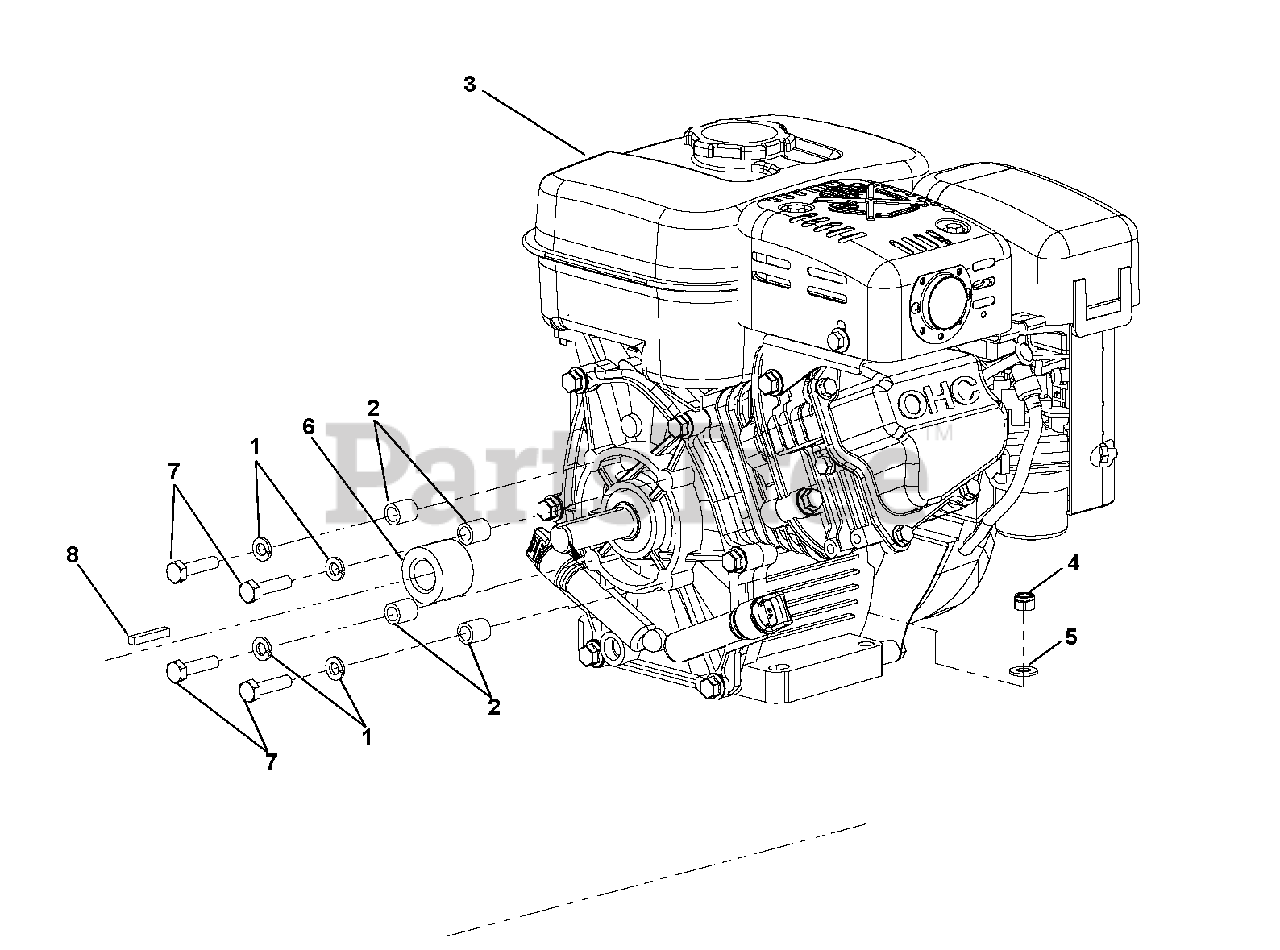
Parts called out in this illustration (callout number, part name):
1	8
2	4
4	8
5	8
